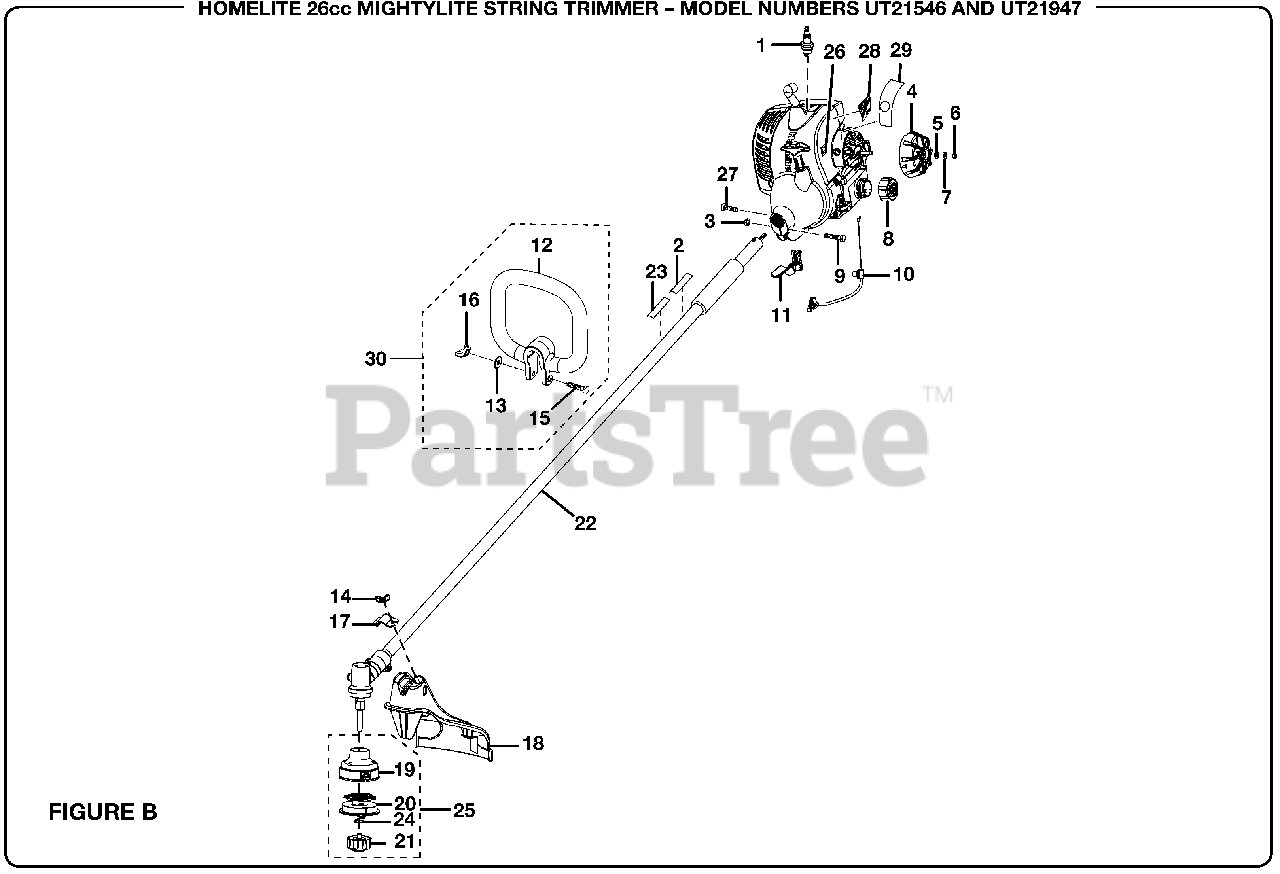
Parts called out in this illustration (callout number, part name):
1	Spark Plug
2	Starting Label
3	Hex Nut (M6)
4	Choke Dial Cover
5	Flat Washer
6	Hex Nut (M4)
7	Wavy Washer
9	Bolt (M6 x 20 mm)
10	Throttle Cable
11	Throttle Trigger
13	Flat Washer
14	Wing Nut (1/4-20)
15	Bolt (1/4-20 x 40 mm)
16	Wing Nut (1/4-20)
17	Mounting Bracket
18	Straight Shaft Grass Deflector
19	Large String Head Housing
20	Dual Line Spool and String
21	Spool Retainer
22	Boom Assembly
23	Warning Label
24	Spring
25	String Head Assembly
26	Switch
27	Screw (8-16 x 5/16 in.)
28	Logo Label
29	Choke Label
30	Handle Assembly
